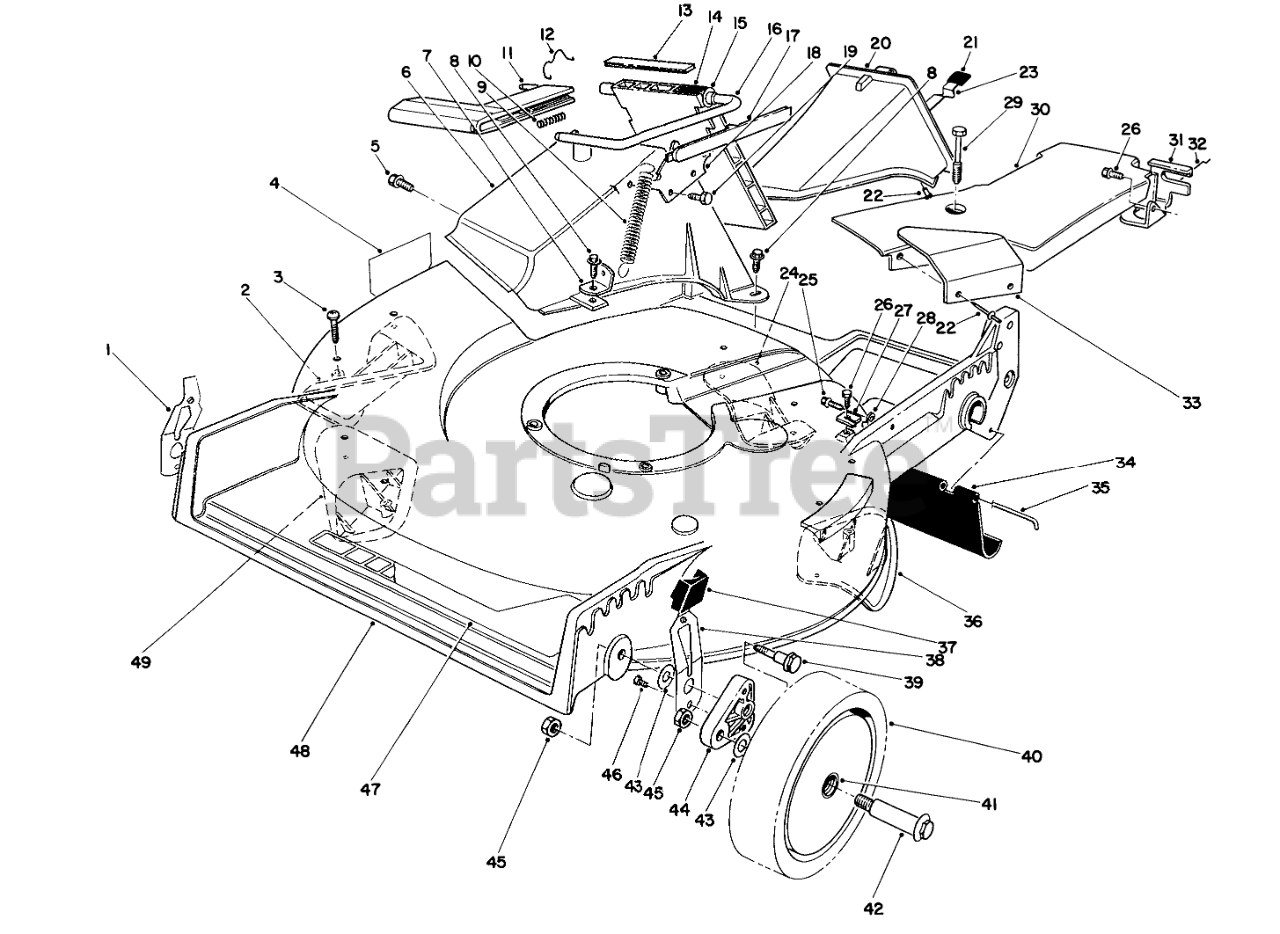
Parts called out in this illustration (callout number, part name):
1	RH SPRING ARM ASSEMBLY
2	KICKER
3	#8 X .625" PHILPS PAN H
4	DECAL-DANGER
5	SCREW AND WASHER ASM
6	Tunnel-Discharge
7	Bracket-Spring
8	SCREW-HWH
9	SPRING-DOOR
10	Spring
11	Handle-Door
12	DOOR RET SPRING
13	Cover-Door
14	Door-Discharge
15	BUSHING-NYLON
16	Rod-Door
17	Cover-Handle
18	DOOR LATCH PLATE
19	SCREW-PLASTITE
20	Plug
21	GRIP-LATCH
22	RIVET-HEAD, FLAT
23	LATCH-PLUG, DISCHARGE
24	KICKER
25	SCREW
26	SCREW-HWHTF
27	CLAMP-CABLE
28	CLAMP-CABLE
29	SCREW-HHFTF
30	Belt Cover Assembly (Incl. Ref. #22 & 33)
31	Bracket-Traction Adj.
32	RETAINER-CABLE
33	HEAT SHIELD
34	SHIELD-TRAILING
35	ROD-SHIELD
36	KICKER
37	KNOB-ARM
38	LH SPRING ARM ASSEMBLY
39	SCREW-SHOULDER
40	Wheel & Tire Assembly (Incl. Ref. #41
41	BUSHING
42	WHEEL BOLT
43	WASHER
44	ARM-PIVOT, FRONT
45	Nut
46	SCREW-HWH
47	DECAL - DECK
48	Housing Assembly (Incl. Ref. #4)
49	KICKER
